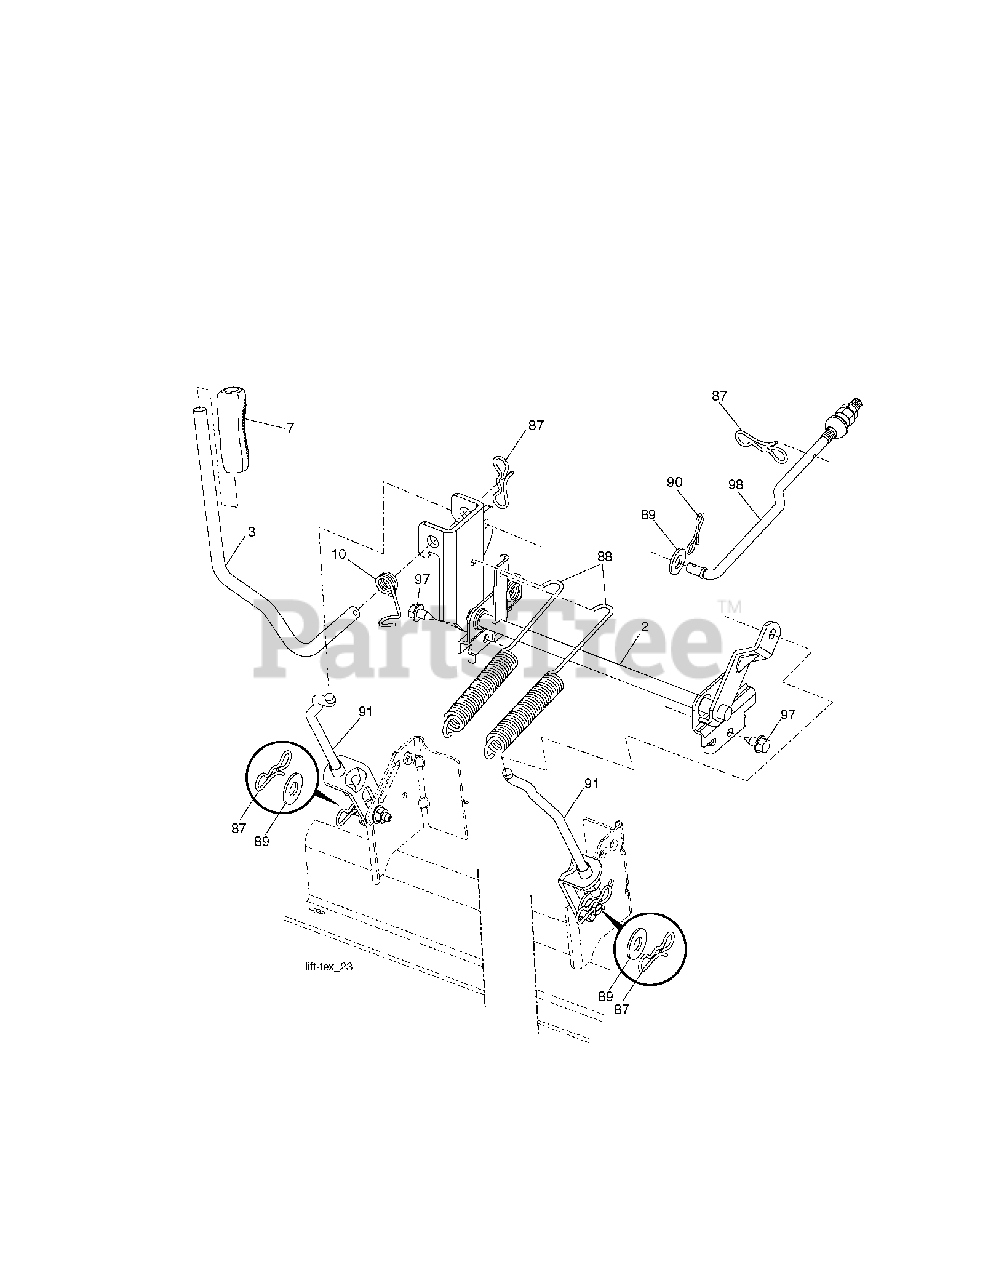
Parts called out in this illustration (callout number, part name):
2	SHAFT.ASM.CROSS.LIFT
3	LEVER.LIFT.HANDLE.LT
7	GRIP.HANDLE.LIFT.PVC.BLACK
10	SPRING.TORSION.LIFT.HANDLE
87	PIN.COTTER.7/16.BOW TI.
88	SPRING.LIFT.ASSIST
89	WASHER.CLEAR.ZINC
90	PIN.COTTER.5/16.BOW TI
91	LINK.ASM.LIFT.54"TG
97	SCREW, 3/8-16X3/4
98	LINK.ASM.SUSP.FRONT.MWR.10.5
